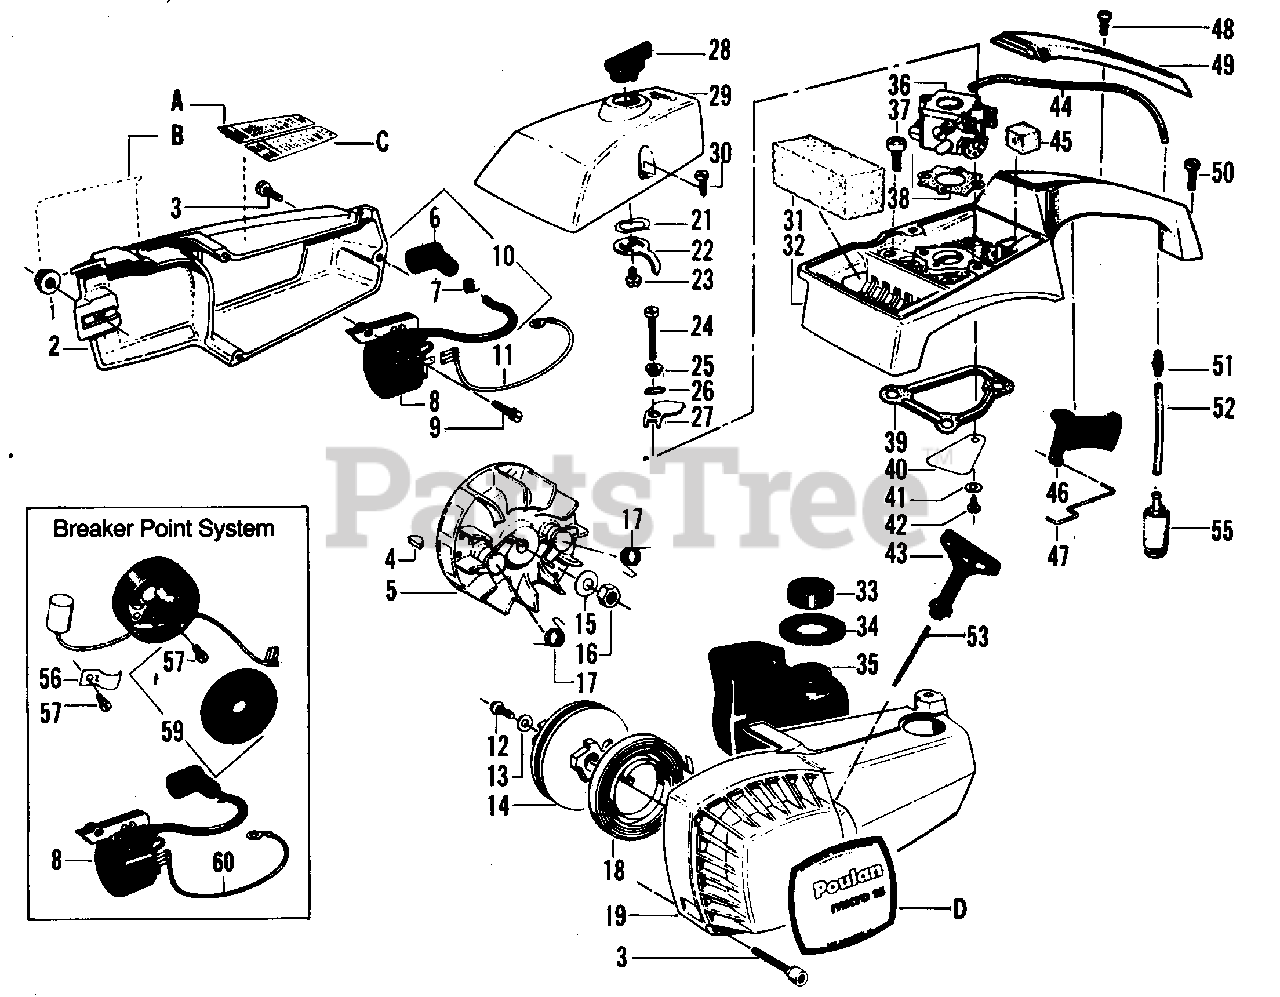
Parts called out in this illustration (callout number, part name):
1	Nut - Bar Mounting
2	Bar Clamp
3	Kit - Fan Housing Screws
4	Key - Flywheel
5	Flywheel Ass'y, Breaker Point Models (Inc.17)
5	Flywheel Ass'y, Solid State Models (Inc.17)
6	Boot Spark Plug
7	Connector - Spark Plug
8	Ignition Module, Coil Ass'y - Breaker Point Models (Inc. #60)
8	Kit Module - Solid State Models (Inc. #10 & 11)
9	Screw - 8 - 32 x 1/4 Fil. Hd. Sems
10	Lead Ass'y. Spark Plug (Inc. 6 & 7)
11	Lead - Switch - See Service Ref. 2
12	Screw 10 - 24 x 1/2 Hex Head
14	Kit - Pulley Replacement (Inc. 13,43,53)
15	Washer - Flywheel
16	Nut 5/16 - 24
17	Spring - Starter Dog
18	Spring Starter
19	Fan Housing
21	Wave Washer
22	Lever - Choker
23	Screw - 8 - 32 x 5/16 Hex Head
24	Screw 10 - 24 x 1-5/8 Fil. Head
25	Spacer - Choke Shutter
26	Wave Washer
27	Shutter Choke
28	Choke Knob
29	Cover - Carburetor
30	Screw 10 - 24 x 5/8 Fil. Head
31	Air Filter
32	Handle & Carburetor Housing
33	Cap - Fuel Tank
34	Seal Fuel Tank Neck
35	Fuel Tank
36	Carburetor
37	Screw - 1/4 - 20 x 11/16
38	Gasket - Carburetor
39	Gasket Carburetor Housing
40	Reed Valve
41	Washer Reed Valve
42	Screw No. 6 x 5/16 Phillip Pan Head
43	Handle - Starter
44	Fuel Line (Bulk No. 8133)
45	Boot - Throttle Wire
46	Trigger Throttle
47	Wire Throttle
48	Screw - No. 8 x 1/4 Phillip Pan Hd.
49	Cover Handle
50	Screw 1/4 - 20 x 1/4
51	Fitting Fuel Line
52	Line Fuel Pick-up (Bulk No. 8133)
53	Rope (3 ft.)
55	Fuel Pick-up Ass'y.
56	Clamp - Connector
57	Screw 8 - 32 x 5/16
59	Breaker Point Ass'y.
60	Lead - Switch
A	Decal Instruction (Right Half)
B	Decal - Bar Clamp - 10"
C	Decal Instruction (Left Half)
D	Decal - Fan Housing - 10"
